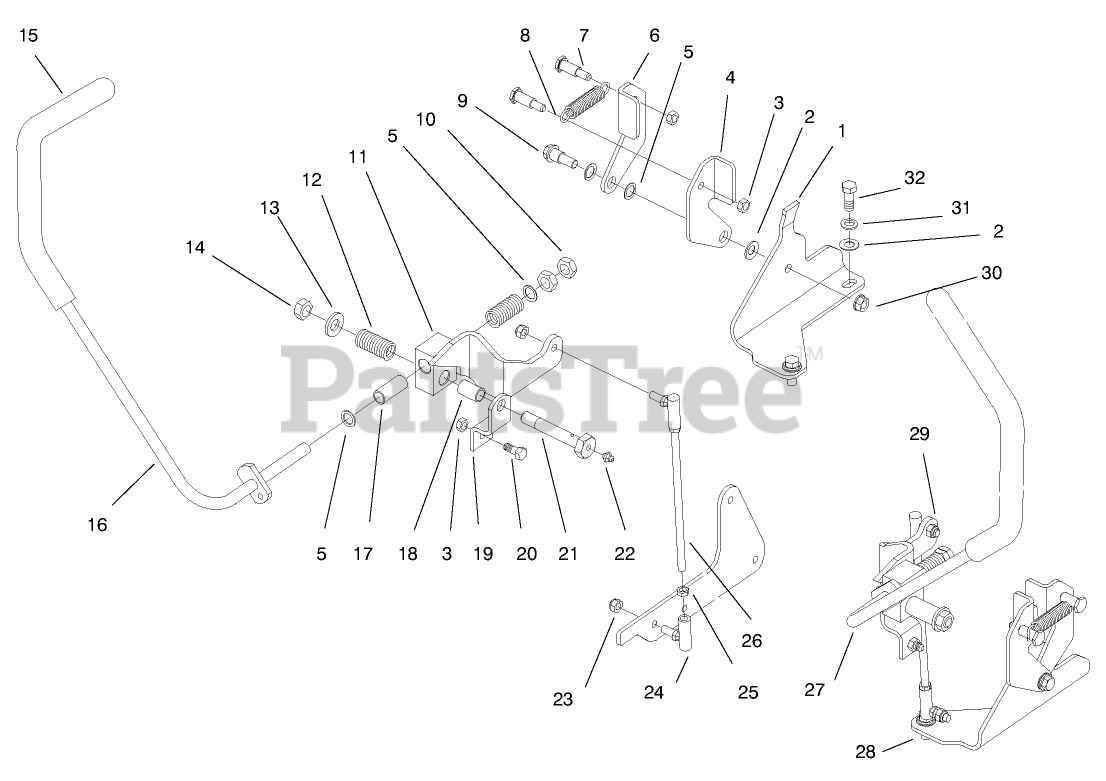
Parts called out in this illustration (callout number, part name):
1	Bracket-Neutral
2	WASHER-FLAT
3	NUT-LOCK, NI
4	Lever-Neutral
5	WASHER
6	Lever-Neutral
7	SCREW-SHOULDER
8	SPRING - EXTENSION
9	BOLT-SHOULDER
10	NUT-JAM
11	Steering Arm ASM
12	SPRING
13	WASHER-FLAT
14	NUT-LOCK, NI
15	GRIP - CUSHION
16	RH Lever ASM
17	BUSHING-STR LVR PVT
18	BUSHING
19	STRAP-PIVOT B
20	SCREW-HH
21	BOLT-STEERING LEVER
22	FITTING-GREASE
23	NUT-LOCK
24	BALLJOINT-RH (W/GROMMET)
25	NUT-JAM
26	ROD - STEERING CONTROL
27	LH Lever ASM
28	Bracket-Neutral
29	Steering Arm ASM
30	NUT-LOCK, NI
31	WASHER-LOCK
32	SCREW-HH
34	CATALOG - PARTS
35	Packaging Instructions
